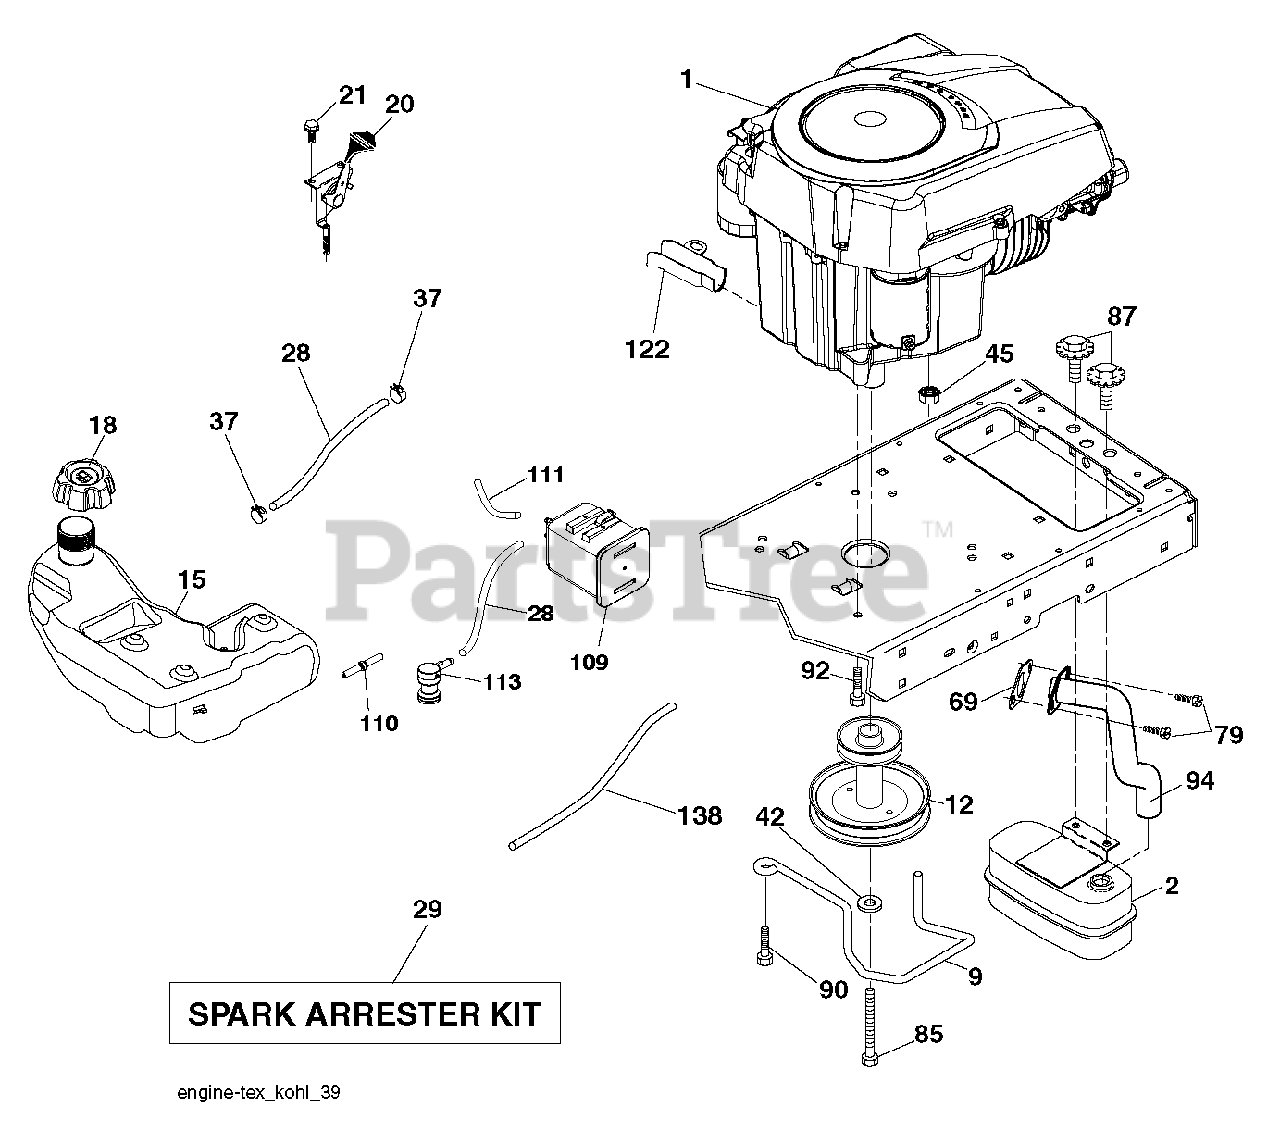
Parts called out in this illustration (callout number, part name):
2	MUFFLER.ASM.SNGL.XTNDED.DFLCTR
9	KEEPER.BELT.ENGINE.3.25 (3 2)
12	PULLEY ENGINE
15	TANK ASM.FUEL.3
18	CAP.ASM.FL.RITCH.3"E10.SYM.498
20	CONTROL.TH/CK.COBRA.KO
21	SCREW.#10 X 0.750.BOS
28	LINE.FUEL.64"REAR.EMIS
29	SPARK ARRESTOR KIT
37	HOSE CLAMP
42	LOCKWASHER
45	NUT
69	GASKET.EXHAUST.KOHLER
79	SCREW.SOCKET HD.5/16-1
85	BOLT HEX 7/16-20X4-1/4"
87	BOLT, 5/16-18 X 1 3/4
90	SCREW 3/8-16X1
92	SCREW 3/8-16X1
94	RP.TUBE.EXHAUST.KOHL.COURAGE
109	CANNISTER, CARBON
110	VALVE.ASM.ANTI-SLOSH
111	PURGE.LINE.36"REAR.CALIFORNIA
113	VALVE.SLANT.CARTRDG.90 DEG.TEX
122	EXTENSION DRAIN OIL
138	RP PURGE LINE
